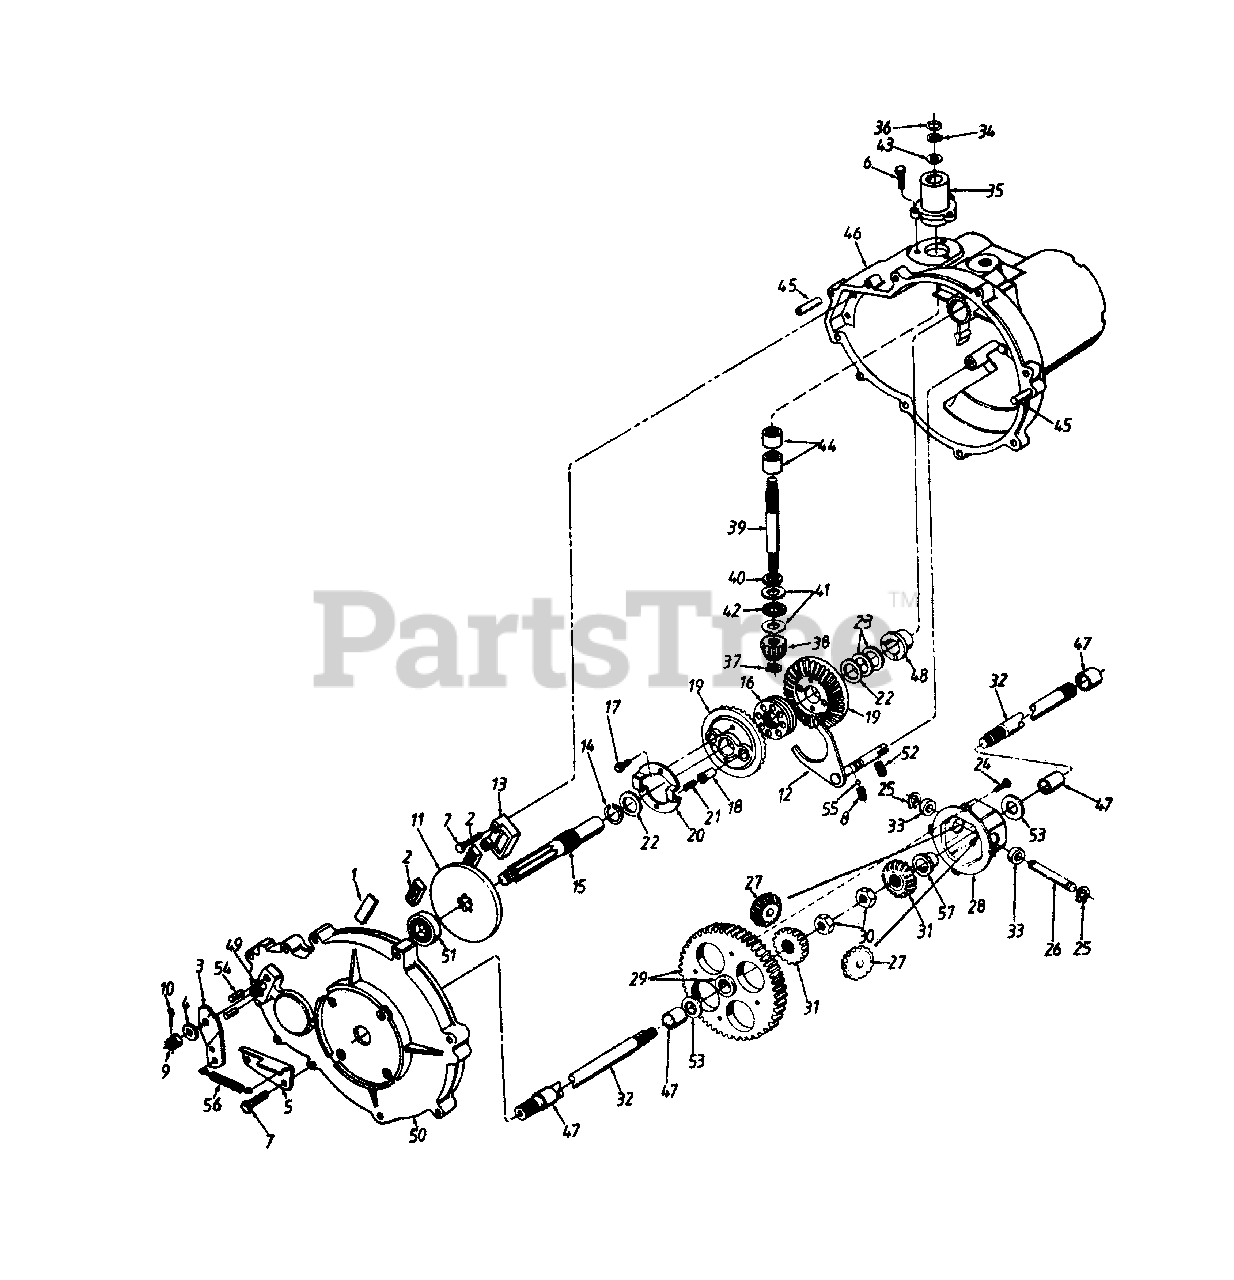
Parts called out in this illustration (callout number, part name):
1	Puck Plate
2	Brake Puck
3	Actuating Arm
4	Fl-Wash. 11/32" I.D. x 7/8" O.D.
5	Brake Stop Brkt.
6	Hex Bolt 1/4-20 x .62" Lg. (Special)
7	Hex Tap Scr. 1/4-20 x 1.25" Lg.
8	Spring Detent
9	Castle Nut 5/16-24 Thd.
10	Cotter Pin 3/32" Dia. x 1" Lg.
11	Brake Disc
12	Shifter Ass'y.
13	Brake Puck Holder
14	Retaining Ring
15	Shaft Drive
16	Shift Collar
17	Hex Wash. Hd. Tap Scr. 1/4-20 x .38" Lg.
18	Drive Pin
19	Bevel Gear Ass'y.
20	Spring Retaining Plate
21	Drive Spring
22	Fl-Wash. .915" I.D. x 1.5" O.D.
23	Fl-Wash. .915" I.D. x 1.37" O.D.
24	Pan Hd. Scr. 1/4-20 x .5" Lg.
25	Snap Ring
26	Cross Shaft
27	Miter Gear 15T
28	Differential Can Assembly
29	Differential Gear Ass'y. w/Bearing
30	Hex Ins. L-Nut 1/2-20 Thd.
31	Miter Gear
32	Axle
33	Differential Thrust Spacer
34	Retainer Ring
35	Input Bearing Housing
36	Wire Ring
37	Retaining Ring
38	Pinion Input 14T
39	Input Shaft
40	Seal 5/8" I.D.
41	Thrust Wash. .621" I.D. x 1.12"
42	Thrust Bearing
43	Fl-Wash. 5/8" I.D. x 1.0" O.D.
44	Needle Brg. 5/8" x 1/2" Lg.
45	Dowel Pin
46	R.H. Housing
47	Sleeve Bearing 3/4" I.D.
48	Flange Bearing .906" I.D.
49	Sq. Head Bolt 5/16-24 Thd.
50	L.H. Housing
51	Ball Bearing .669" I.D.
52	Set Screw 5/16-18 x 3/8" Lg.
53	Fl-Wash. .76" I.D. x 1.5" O.D.
54	Brake Actuating Pin
55	Ball Detent
56	Ext. Spring 1.14" Lg.
57	Differential Flange Brg.
